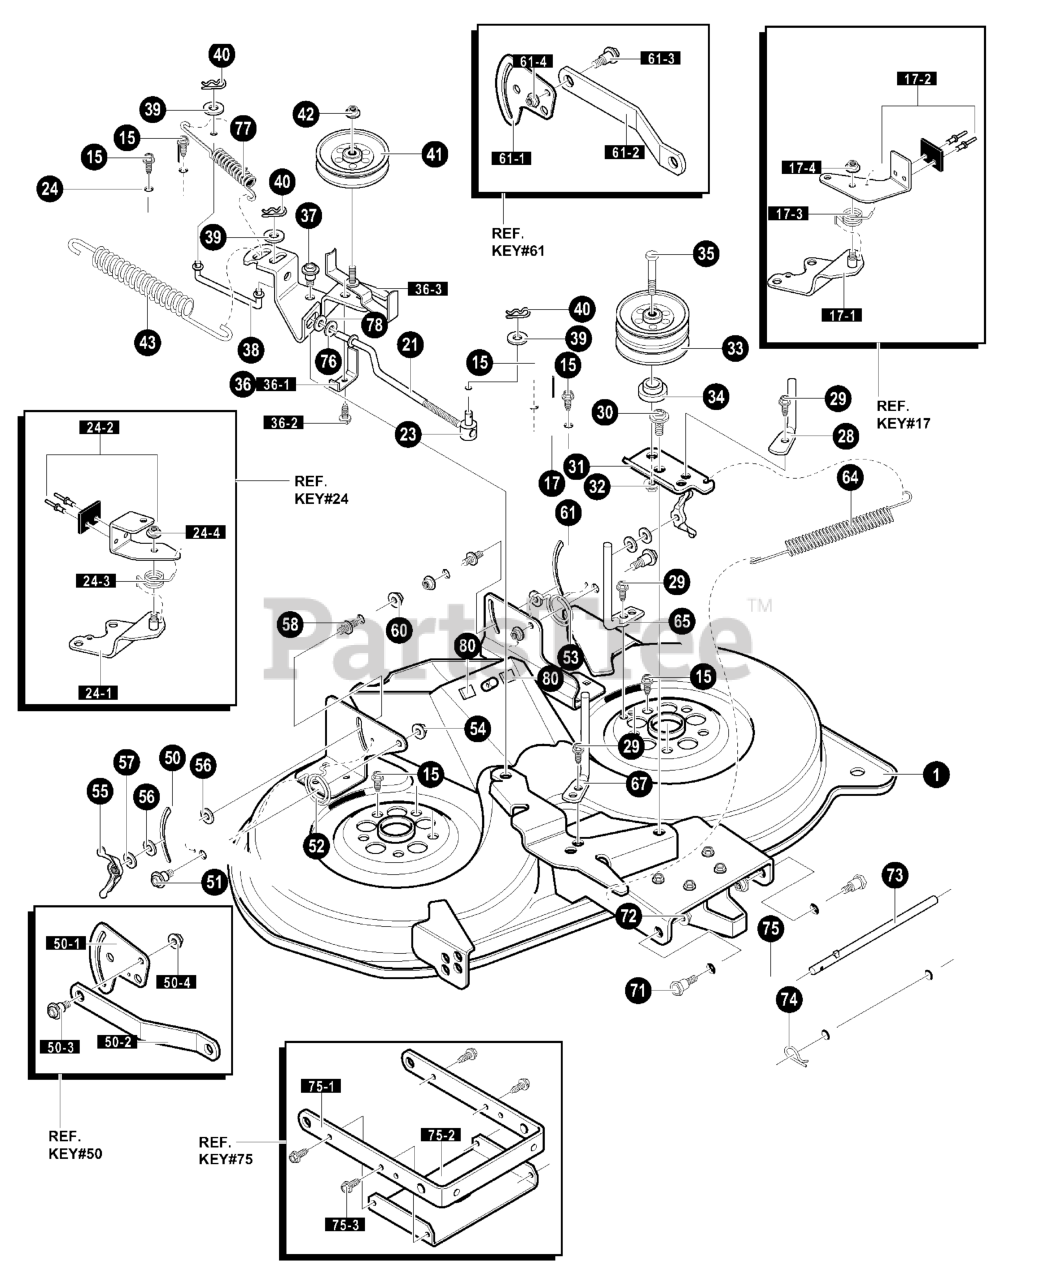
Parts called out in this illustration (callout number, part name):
1	HOUSING, 40" DECK
17	BRAKE ARM ASSEMBLY LH
17-1	BRAKE SUPPORT ASSEMBLY LH
17-2	BRAKE ARM ASSEMBLY LH
17-3	SPRING, TORSION
17-4	NUT, 5/16-18
21	LINK, BRAKE LH
23	NUT, ADJUST
24	BRAKE ARM ASSEMBLY RH
24-1	BRAKE SUPPORT ASSEMBLY RH
24-2	BRAKE ARM ASSEMBLY RH
24-3	SPRING, TORSION
24-4	NUT, 5/16-18
28	GUIDE, BELT
29	SCREW, 5/16-18 x 0.50
30	BOLT, SHOULDER
31	ARM, DOUBLE IDLER
32	NUT, 3/8-16
33	PULLEY,IDLER DOUBLE VEE
35	Screw, 3/8-16 x 3.00
36	IDLER ARM ASSY
36-1	SPRING - GUIDE BELT
36-2	SCREW, 1/4-20X .50
36-3	IDLER ARM ASSEMBLY
37	BOLT., SHOULDER
38	LINK, BRAKE RH
39	WASHER, FLAT .375X.87 INSULATE
40	PIN, HAIR
41	PULLEY, V IDLER 4"
42	NUT,3/8-16
43	SPRING, EXTENSION
50	ASSEMBLY, PLATE,REAR SUS.BRKT.RH
50-1	PLATE - SUSPENSION
50-2	SUSPENSION BRACKET REAR
50-3	BOLT, SHOULDER
50-4	NUT,3/8-16
51	BOLT, SHOULDER
52	SPRING, TORSION RH
53	SPRING, TORSION LH
54	NUT,3/8-16
55	WINGNUT, 5/16-18
56	PAD, FRICTION
57	WASHER
58	PIN, HANGER
60	NUT, 3/8-16
61	ASSEMBLY, PLATE, REAR SUS.BRKT.LH
61-1	PLATE - SUSPENSION
61-2	SUSPENSION BRACKET, REAR
61-3	BOLT, SHOULDER 3/8-16
61-4	NUT,3/8-16
64	SPRING, EXTENSION
65	GUIDE, BELT
67	GUIDE, BELT
71	BOLT, SHOULDER
72	NUT, 3/8-16
73	ROD, HANGER
74	PIN, HAIR
75	ASSEMBLY, BRACKET & STIFFENER
75-1	BRACKET, FRONT SUSPENSION
75-2	STIFFENER
75-3	SCREW, 5/16-18 x 0.75
77	SPRING, EXTENSION
78	WASHER, FLAT .375X.87 INSULATE
80	PAD, ADHESIVE 1.00X1.50X.12
